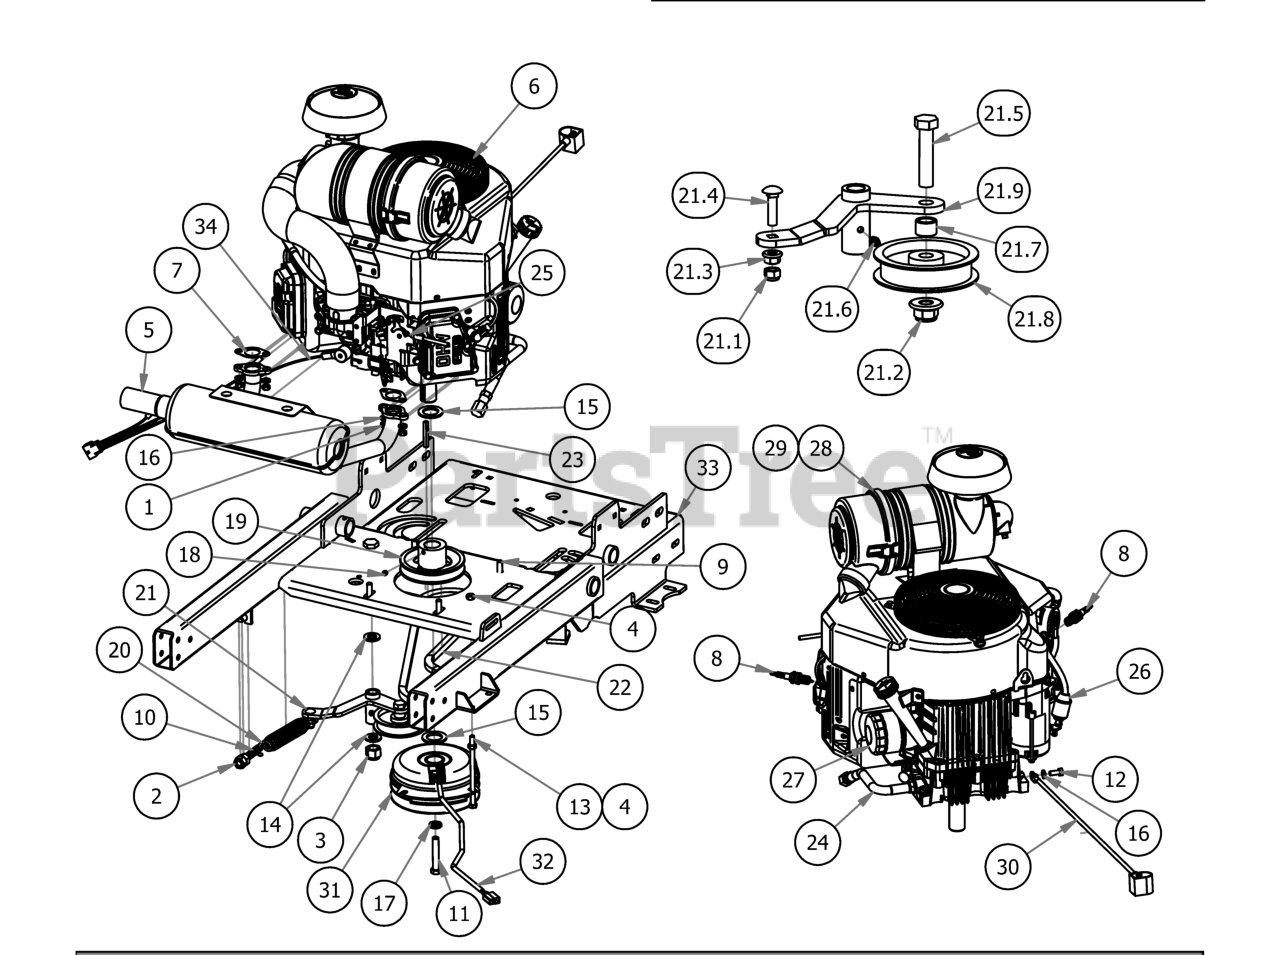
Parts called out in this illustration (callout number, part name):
1	M8-1.25 Zinc Nut
2	1/2" Hex Nut
3	5/8 Std NC Nylock Nut
5	Exhaust-Stand On-FX691V Kawasaki
7	Exhaust Gasket
8	Spark Plug - Kawasaki
9	3/8 x 1 1/8 bolt
10	All Thread-Pump Idler Tensioner
11	7/16" x 2 1/2" Hex Bolt
12	M8x1.20x20MM Hex head bolt
13	5/16-18 x 5-1/2 GR 5 Hex Bolt
14	.630 ID Plastic Washer
15	1 1/8" Flat Spacer
16	5/16" Lock Washer
17	7/16" Lock Washer
18	5/16 Set Screw
19	4 3/4 Motor Pulley
20	Deck Idler Spring
21	2020 36" Stand-On Drive Belt Pulley Assembly
21.1	5/16-18 Nylock Insert Locknut
21.2	1/2-13 Nylon Flange Nut
21.3	5/16" Flange Nut
21.4	5/16" x 1 1/4" Carriage Bolt
21.5	1/2-13X 2-1/4 GR Hex Bolts
21.6	1/4" Press in Grease Fitting
21.7	1/2 x 1/2 Spacer
21.8	3.25 Flat Idler Pulley
21.9	36 Pump Idler Arm Weldment
22	2019 Renegade Pump Belt
23	1/4 x 2 Square key Stock
24	Oil drain Hose
25	Outlaw Throttle Cable
26	Universal Inline Fuel Filter
27	Kawasaki Oil Filter
28	Canister Air Filter- Outer
29	Canister Air Filter- Inner
30	24" Black Ground Cable
31	Clutch Assembly
32	Clutch Pigtail
33	2020 36 Stand On Frame Weldment
34	Harness Adaptor
